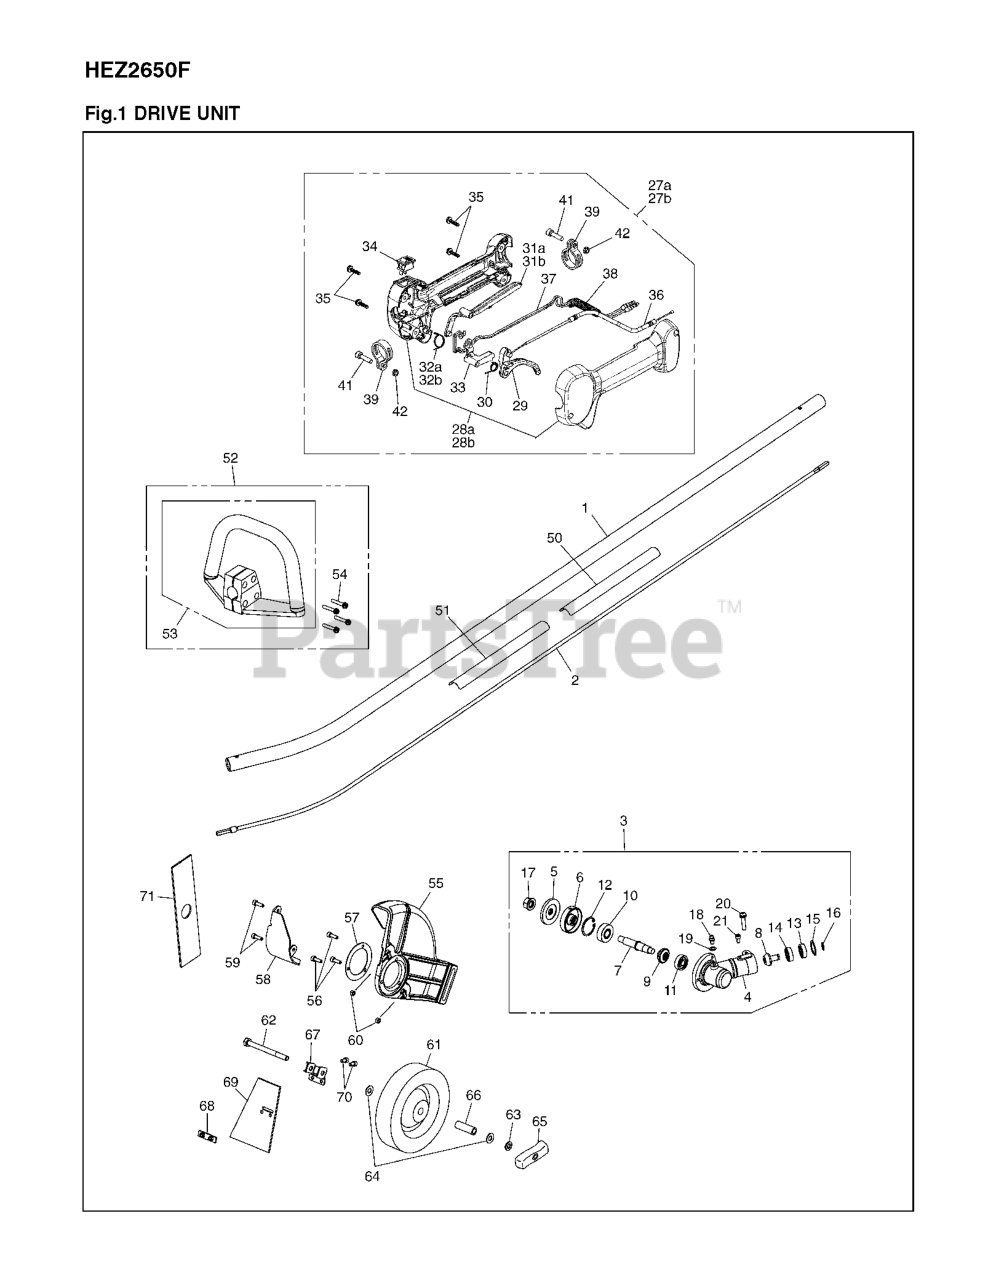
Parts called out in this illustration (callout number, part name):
1	PIPE COMP
2	FLEX SHAFT
3	GEARCASE ASSY
4	GEARCASE
5	HOLDER(B)
6	HOLDER(A)
7	SHAFT.GEAR
10	BEARING***
21	BOLT M5 X L10 ALLEN BOLT
27	GRIP ASSY
28	GRIP HALF SET
29	LEVER, THROTTLE
30	SPRING, THROTTLE
31	LEVER FOR GRIP (RPLS -0600)
31	LEVER, SAFETY
32	SPRING JOINT
32	SPRING
33	LEVER JOINT
37	CORD - C
42	NUT
51	LABEL CAUTON FOR BC
52	HANDLE ASSY. (RPLS T319514001)
53	HANDLE T
55	GUARD
56	BOLT M5 X L16 ALLEN
58	PROTECTOR
59	BOLT M5 X L16 ALLEN
70	BOLT M5 X L10 ALLEN BOLT
